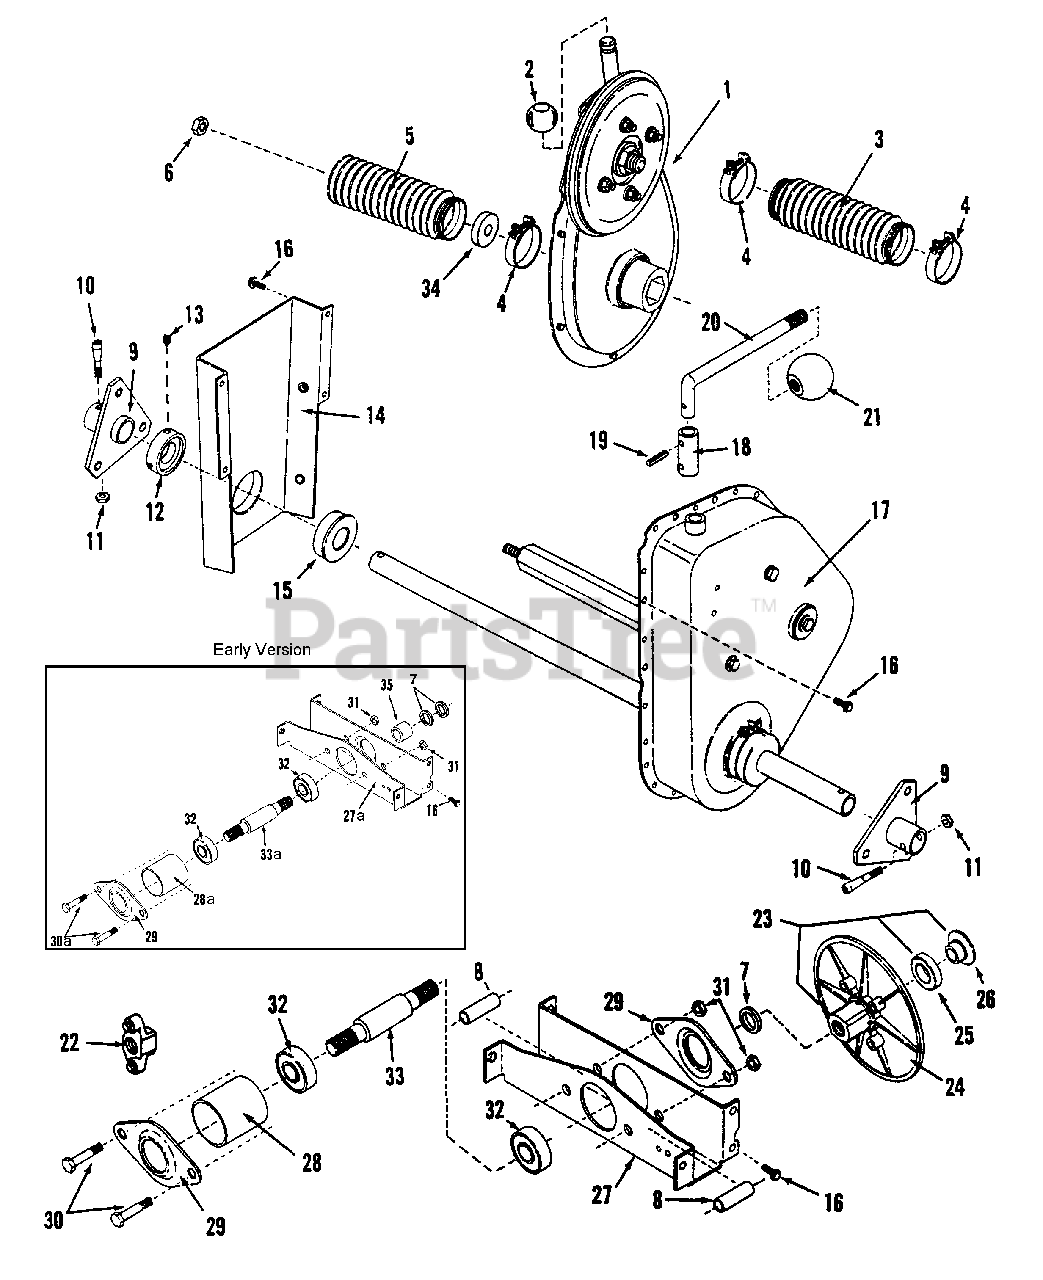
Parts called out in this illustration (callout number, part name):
1	PRIMARY CASE
2	BUSHING, Primary Clutch
3	BOOT, Left Side Oil seal
4	CLAMP, Boot
5	BOOT, Right Side Oil Seal
6	NUT, 3/8-16 Hex Flange Lock
7	WASHER, Shim
8	SPACER, 3.312" Long x .332" ID
9	HUB, Rear Wheel
10	BOLT, Tapered
11	NUT, 5/16-24 Hex Lock
12	LOCK-COLLAR
13	SETSCREW, 5/16-18 x 5/16"
14	ASSEMBLY, Axle Support
15	BEARING, Ball
16	SCREW, 5/16-18 x 5/8" Hex Washer Self-Tap
17	ASSEMBLY, Transmission
18	COUPLING, Shift Lever
19	ROLL-PIN, 3/16 x 3/4"
20	LEVER, Hl-LO Shifter
21	KNOB, Shifter Ball
22	HUB, Flex Coupling
23	ASSEMBLY, Drive Disc
24	DISC, Drive
25	BEARING, Ball
26	BUTTON, Center
27	SUPPORT, Bearing
27A	SUPPORT, Bearing
28	TUBE, Spindle 1.78" ID x 4.075 Long
28A	TUBE, Spindle 1.78" ID x 3.075 Long
29	RETAINER
30	SCREW, 5/16-18 x 4-1/4" Hex Head Cap
30A	CAPSCREW, 5/16-18x3 Hex Head
31	NUT, 5/16-18 Hex Center Lock Grade B or 5
32	BEARING, Ball
33	SPINDLE, Drive Disc 6.04" Long, 2.826" Shoulder
33A	SPINDLE, Drive Disc 6.04" Long, 1.826" Shoulder
34	WASHER, Shim
35	SPACER, .75" ID x 1" Long
